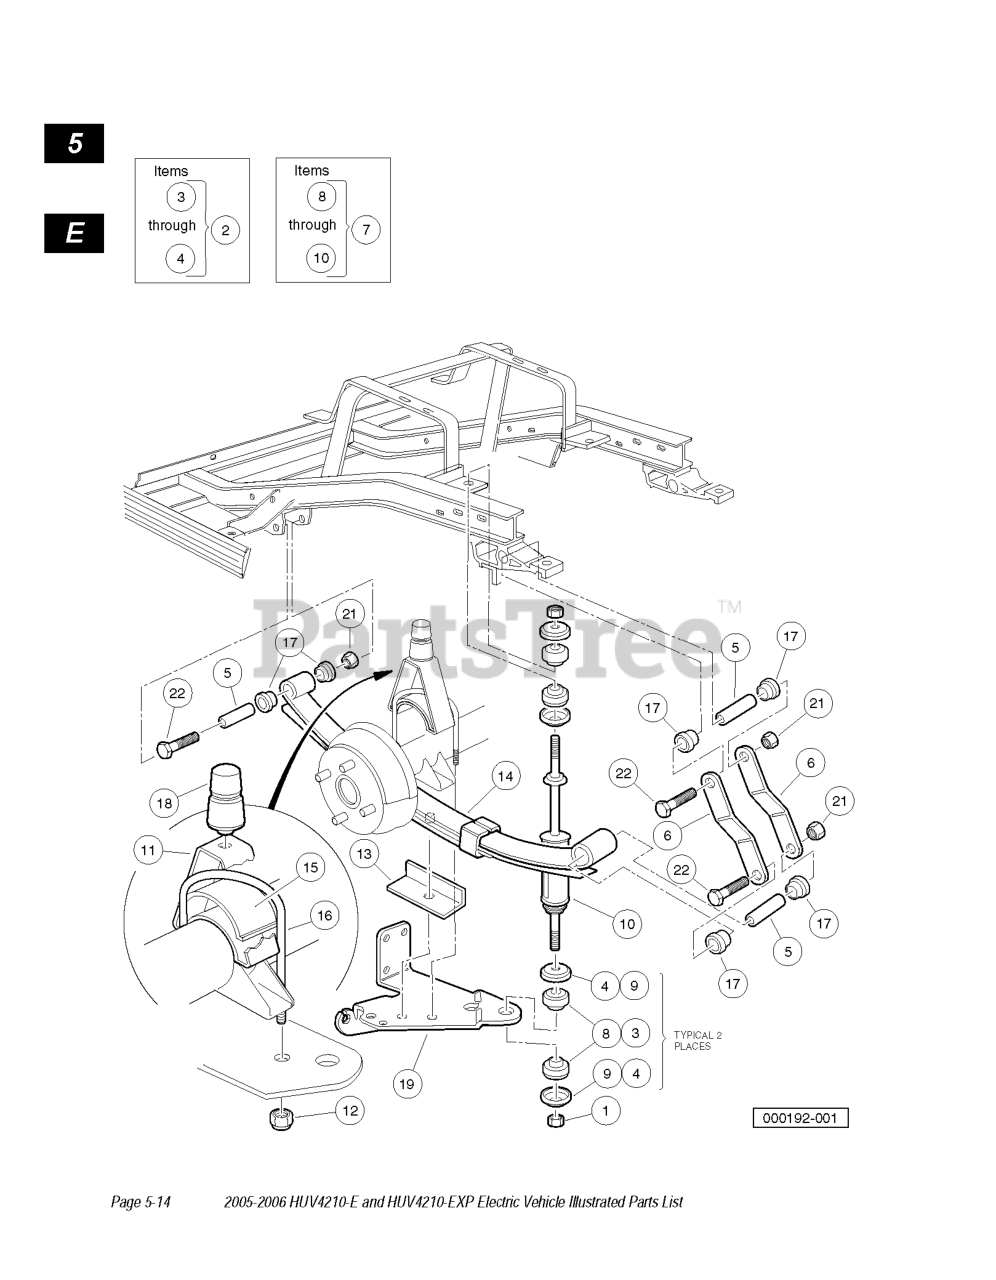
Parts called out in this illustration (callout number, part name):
1	NUT, 3/8-24 HEX
2	SHOCK ABSORBER CUSHION KIT
5	BUSHING - STEEL (GAS CAR)
6	SHACKLE, REAR SPRING -GAS STR
7	SHOCK ABSORBER KIT
10	SHOCK ABSORBER REAR PRV SPD
11	BUMPER MOUNT ANGLED - ELECTRIC
13	SPRING RETAINER
14	REAR LEAF SPRING
15	SPACER - OVERLOAD BUMPER CA
17	BUSHING, URETHANE
18	BUMPER, JOUNCE
19	BRACKET, LEFT HAND
20	BRACKET RIGHT HAND
21	LOCKNUT, 3/8-16 HEX
22	SCREW, 3/8-16 X 3.375
